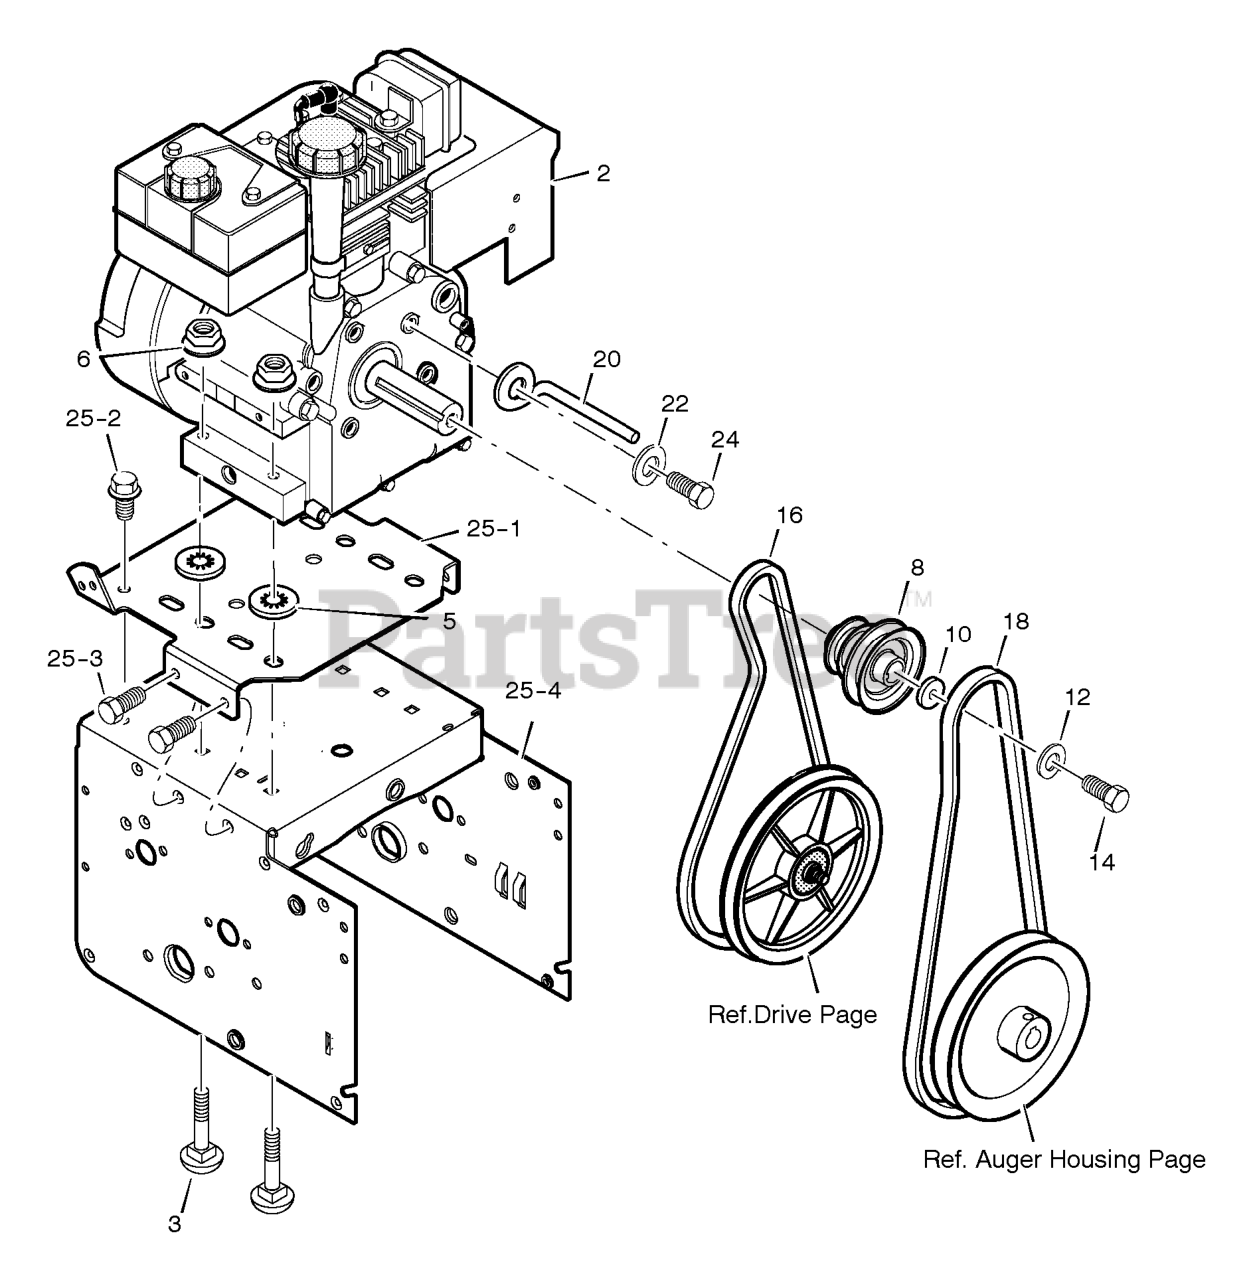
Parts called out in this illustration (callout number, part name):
2	ENGINE
3	BOLT, CARRIAGE 5/16-18
5	RETAINER, PUSH
6	NUT, HEXWDFLLK 5/16-18
8	PULLEY, ENGINE
10	WASHER
12	WASHER,HVSPTLK .38ID
14	SCREW, 3/8-24 x 1.00
16	BELT, V 3L 33.13LG
18	BELT, V 4L35.6 LG
20	GUIDE, BELT
22	WASHER, SPTLK .31X.58X.08
24	SCREW, 5/16-24 x 0.75
25	FRAME, MOTORBOX
25-1	PLATE, ENGINE MOUNT
25-2	SCREW, TAP 1/4-20 X .63
25-3	SCREW, TAP 5/16-18 X .50
25-4	FRAME, MOTOR BOX
